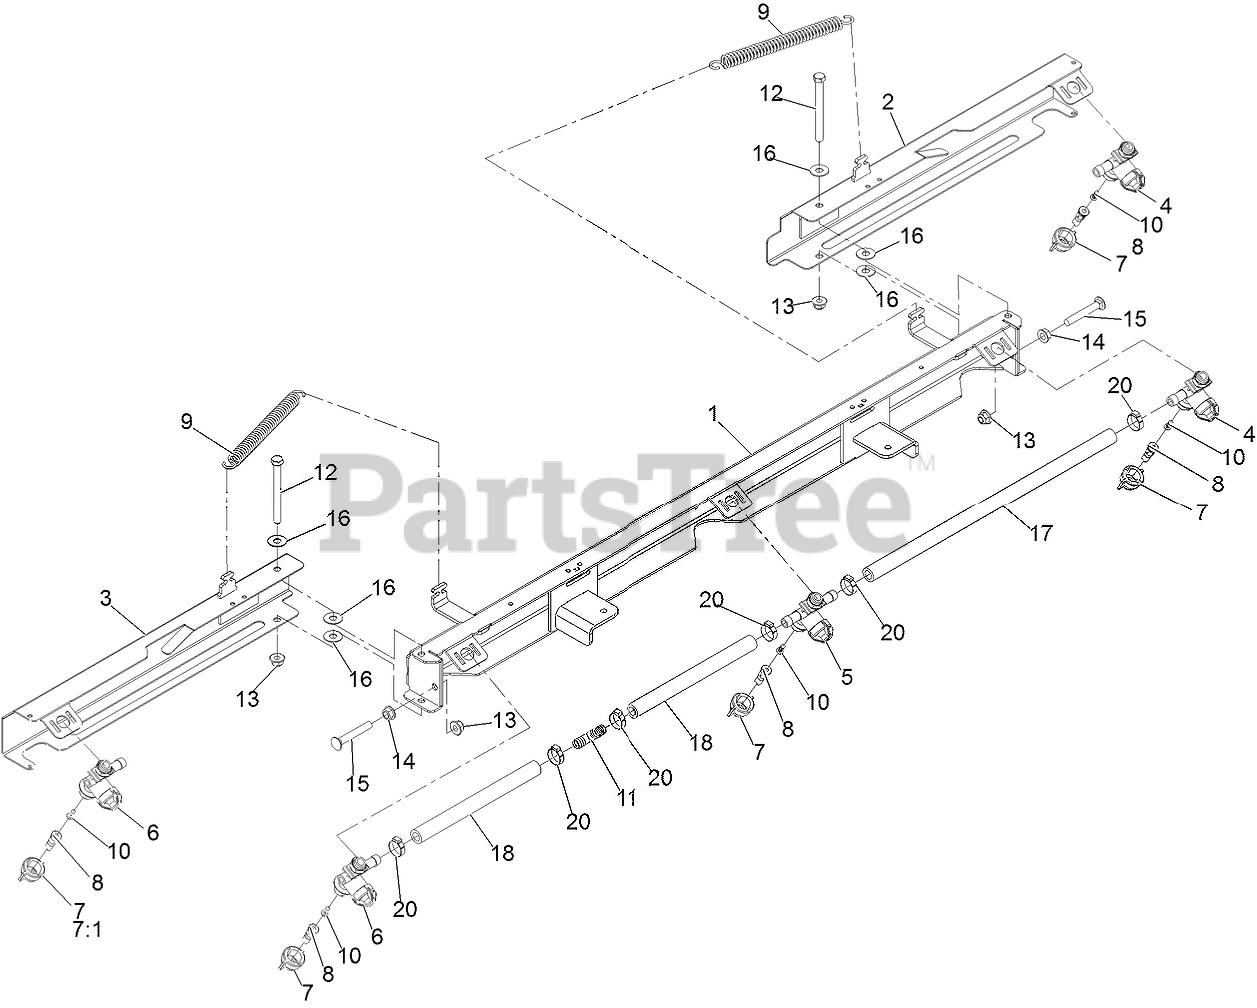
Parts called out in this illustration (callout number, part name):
1	BOOM-CENTER
2	BOOM-WING, RT
3	BOOM-WING, LT
4	BODY-NOZZLE, RIGHT
5	BODY-NOZZLE, CENTER
6	BODY-NOZZLE, LEFT
7	CAP-NOZZLE
7:1	SEAT-GASKET
8	TIP-SPRAY, 025
9	SPRING-EXTENSION
10	STRAINER-NOZZLE, 50M 5PSI
11	FITTING-TEE, BARB
12	SCREW-HH
13	Nut-Hex Flange
14	Nut-Hex Flange
15	SCREW-CARR
16	WASHER-FLAT
17	Hose-Spray
18	Hose-Spray
20	CLAMP-OETIKER, 167
